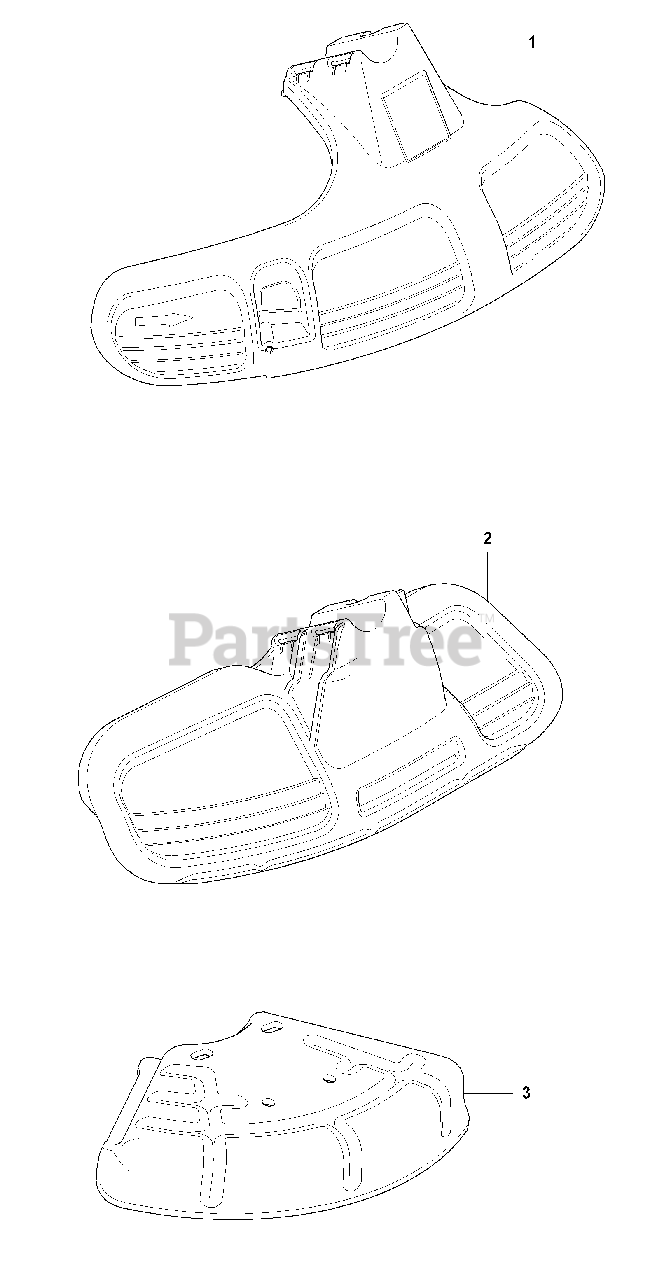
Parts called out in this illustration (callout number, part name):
1	PROTECTION
2	BLADE GUARD GRASS
3	BLADE GUARD SAW
